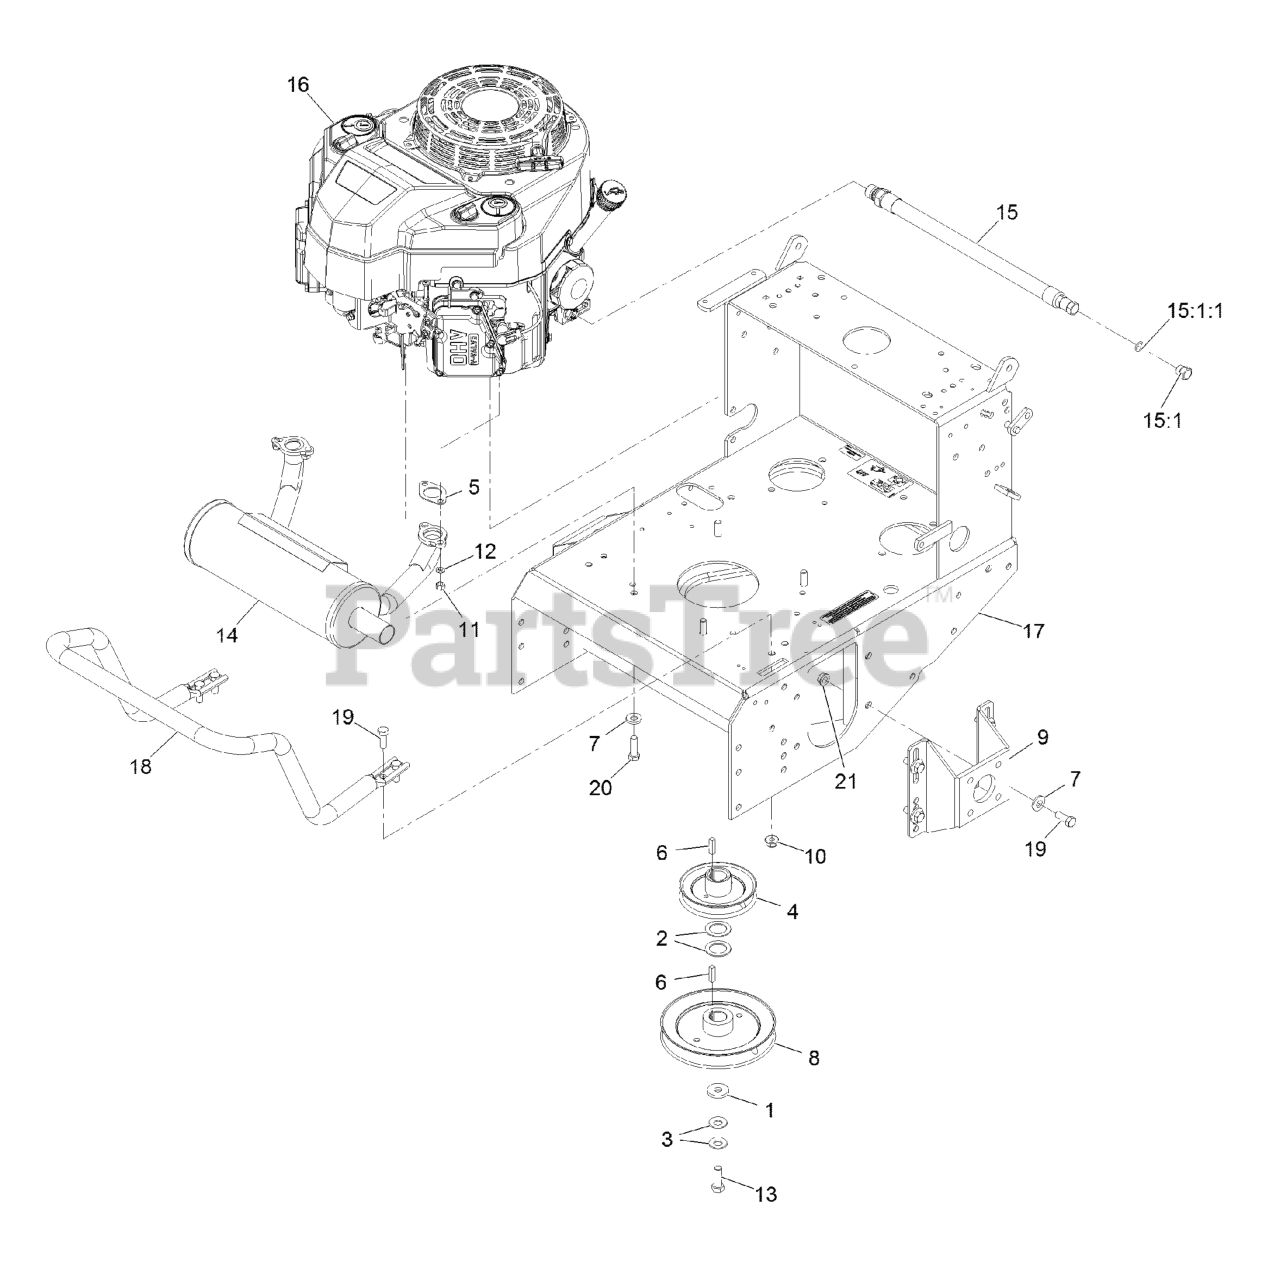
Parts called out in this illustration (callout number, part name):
2	WASHER-SPACER
3	WASHER-SPRING
5	GASKET-EXHAUST
7	WASHER-BELLEVILLE
9	MOUNT-MOTOR
10	NUT-HF, NI
12	WASHER-LOCK
13	SCREW-HH
14	MUFFLER-HORIZONTAL, OFFSE
15	ASM, ENGINE OIL DRAIN HOS
15:1	PLUG-HH
15:1:1	O-RING
16	Engine-Kawasaki
17	ASM, VH ENGINE DECK W/DECALS
18	TUBE-GUARD MUFFLER
19	SCREW-HH
20	SCREW-HH
21	NUT-HHF, WHIZ
